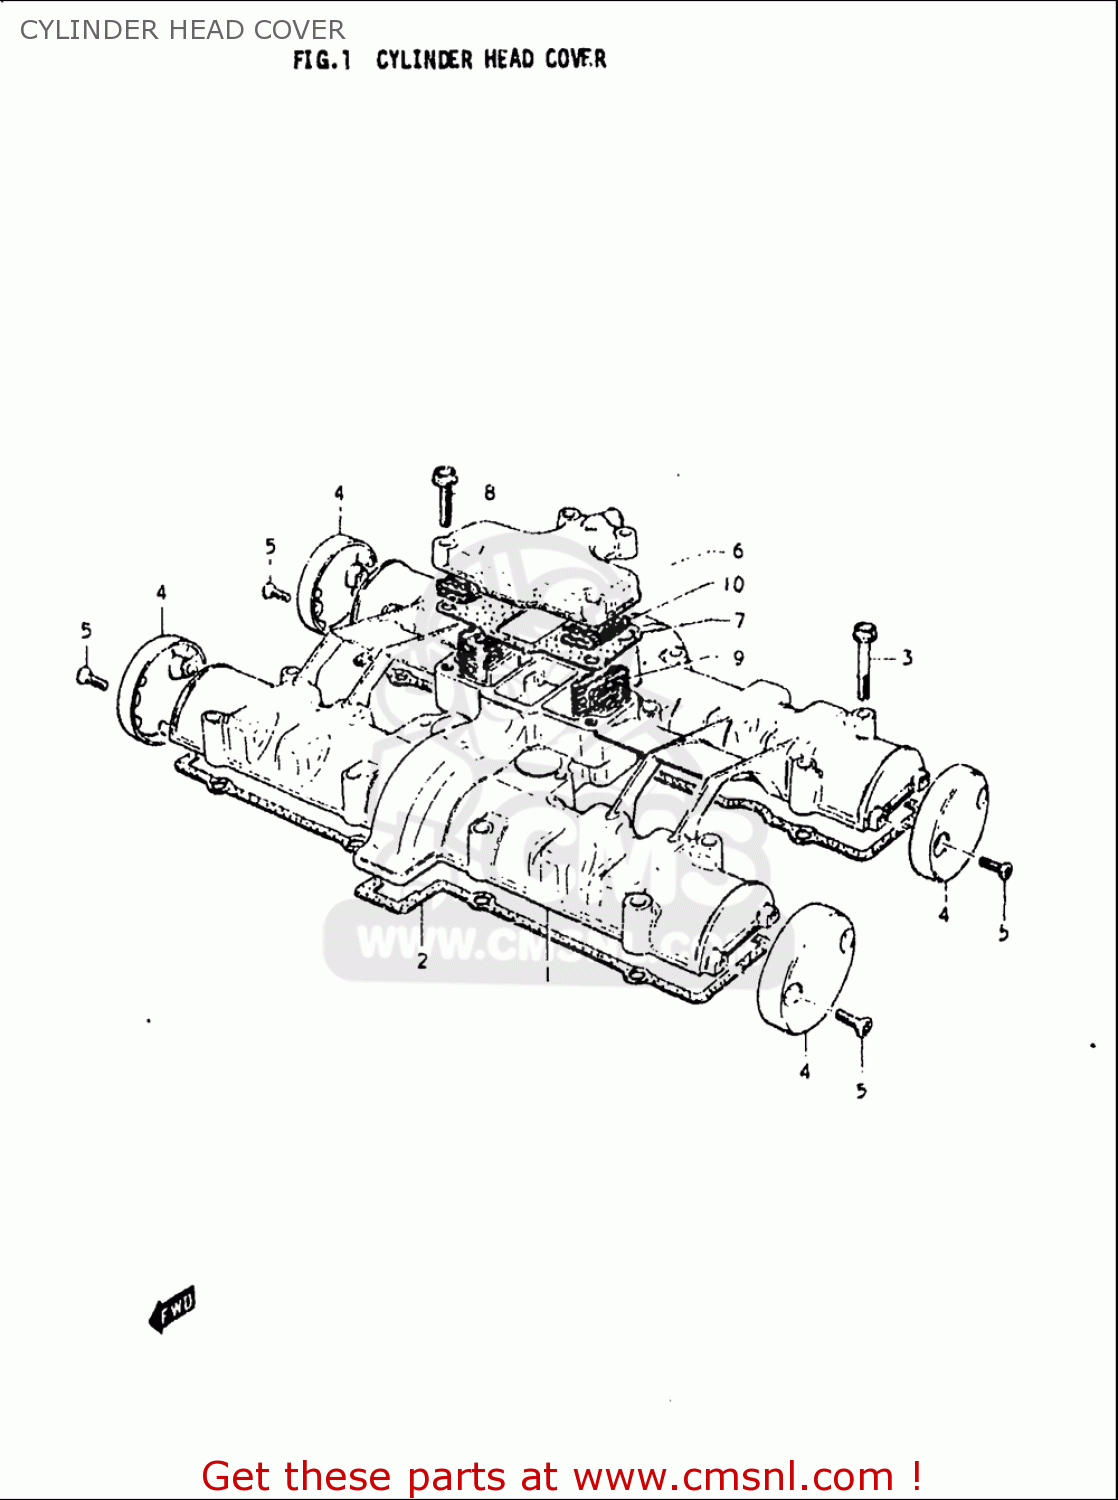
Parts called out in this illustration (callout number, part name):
2	GASKET,CYLINDER HEAD COVER (NAS)
3	BOLT
4	CAP,CYLINDER HEAD COVER
5	SCREW
6	COVER,BREATHER
7	GASKET,BREATHER COVER (NAS)
8	BOLT
9	SEPARATOR,OIL BREATHER
10	SEPARATOR,OIL BREATHER
